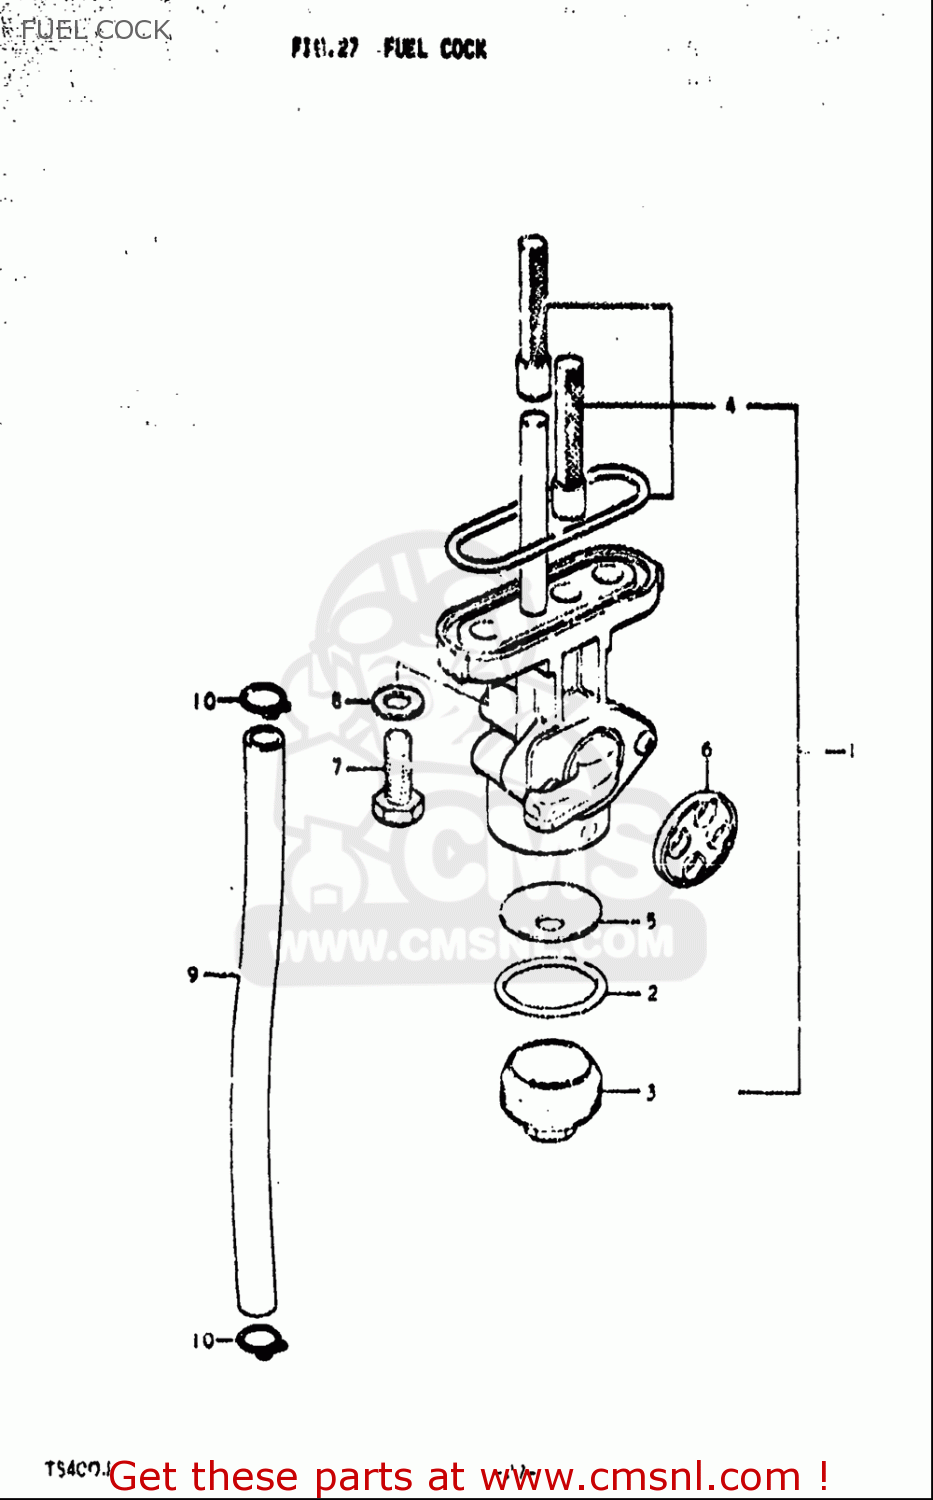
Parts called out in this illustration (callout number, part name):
1	COCK ASSY,FUEL
2	GASKET,FILTER (NAS)
3	CUP,STRAINER
4	FILTER SET,FUEL COCK
5	NET,STRAINER
6	GASKET,LEVER (NAS)
7	SCREW
8	GASKET(5.8X13X1.2) (NAS)
9	HOSE(5X9X600)
10	CLIP
